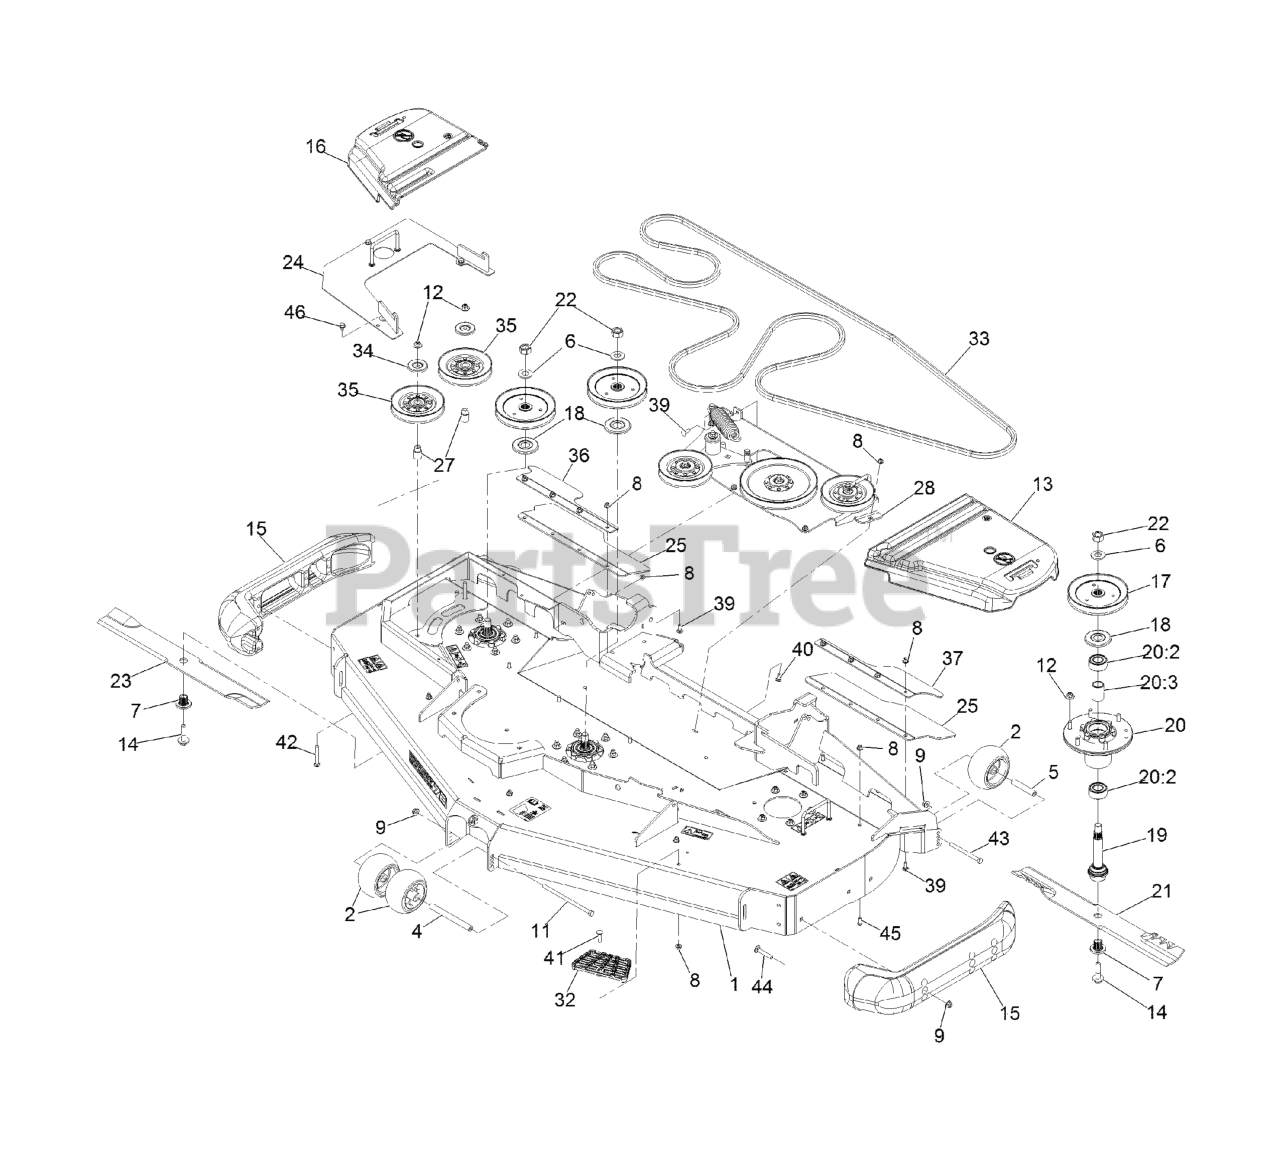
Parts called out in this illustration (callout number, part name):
1	DECK-RD72 W/DECALS
2	ROLLER-SCALP, ANTI
4	SPACER-WHEEL
5	TUBE-SPANNER
7	BUSHING,SPLINED
8	NUT-HF, NI
9	NUT-HF, NI
11	SCREW-HH
12	Nut-Nyloc 3/8-16 Flg
13	COVER-BELT, LH
14	SCREW,SEMS 1/2-20 X 2.19
15	SKID-BUMPER, DECK
16	COVER-BELT, RH
17	SHEAVE,BLADE DRIVE 6.50
18	GUARD-BEARING, TOP
19	ASM-SPINDLE AND SEAL
20	ASM-CUTTER HSG
20:2	BEARING-3205 TRASHGUARD
20:3	SPACER-BEARING
22	NUT-HEX
24	COVER-REVERSE DRIVE
25	GUARD-TIRE
27	STANDOFF-IDLER
28	Idler Mount ASM
32	STEP-DECK
33	BELT-BB
34	SHIELD-DUST
35	IDLER V
36	SUPPORT-FLAP, OUTER (RH)
37	SUPPORT-FLAP, OUTER (LH)
39	SCREW-CARR
40	SCREW-CARR
41	Bolt-Carriage 5/16-18 X 1 1/4
42	SCREW-CARR
43	SCREW-HH
44	Bolt-Carriage 3/8-16 X 2 1/4
45	SCREW-HSBH
